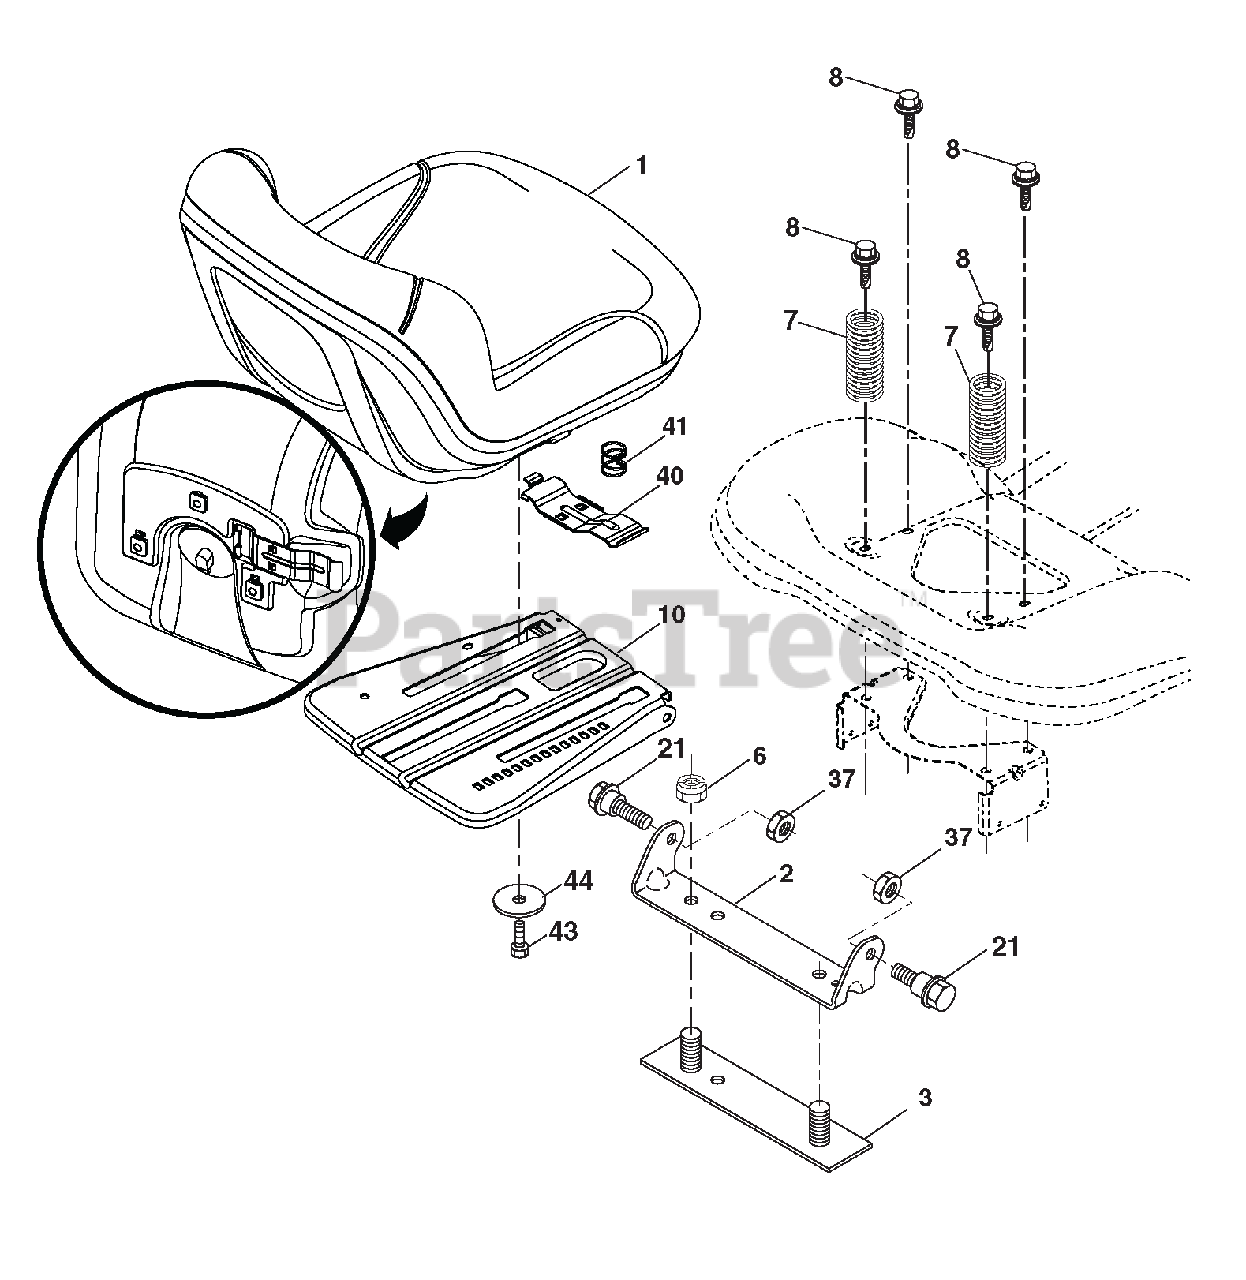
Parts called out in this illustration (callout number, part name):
1	SEAT.TA150.KB/SLD.BLK.ARIENS
2	BRACKET.PIVOT.FENDER.2002
3	STRAP ASM.FENDER.94
6	Locknut, Washer Insert 3/8-16
7	SPRING.SEAT.CPRSN.2.250.BLK.ZI
8	BOLT.5/16-18UNCX3/4 W/SEMS.BLK
10	PAN ASM.SEAT.3PT.
21	BOLT.SHLD.5/16-18 UNC-2A.BLK D
37	Locknut, Washer Insert 5/16-18
40	HANDLE.SLIDE.SEAT.TEX.MILSCO
41	SPRING.LATCH.SEAT.TEX
43	BOLT.FIN.HEX.3/8-16UNC X 3/4
44	WASHER.13/32 X 2 3/8 X 12GA.
